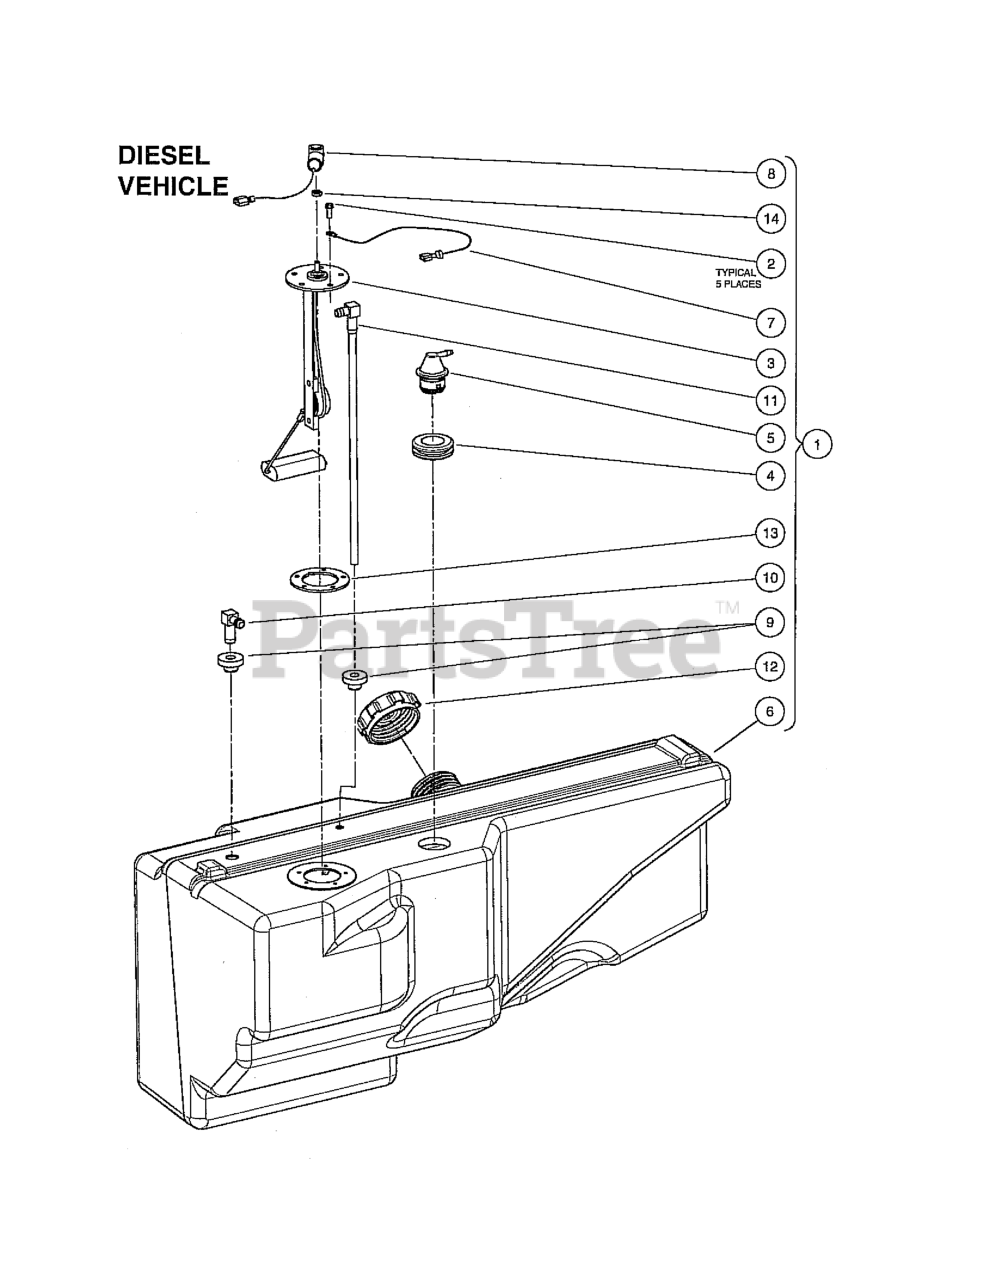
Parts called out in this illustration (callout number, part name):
1	ASM, TANK, DIESEL, SIDEFILL
4	INSULATION GROMMET
5	FUEL TANK VENT ASSY
9	BUSHING, LINE, RETURN
10	ELBOW, 90 BARBED
11	PICKUP TUBE, FUEL
12	ASM, CAP, FUEL, DIESEL, PTD
13	GASKET, SEND UNIT (RUBBER)
14	NUT, #10-32 BRASS HEX
